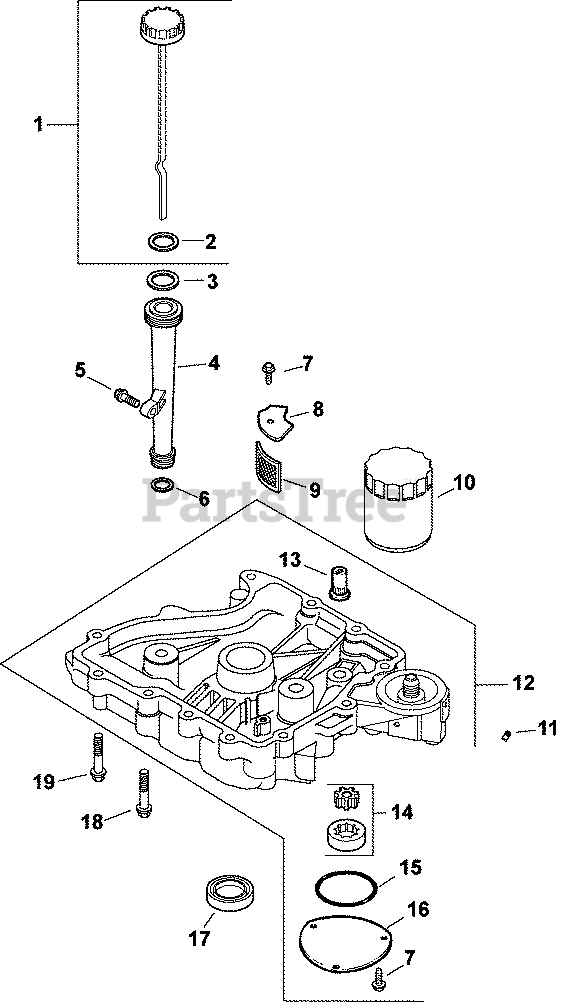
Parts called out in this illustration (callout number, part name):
1	DIPSTICK/CAP ASSY (BLACK)
2	O-RING, DIPSTICK
3	O-RING, UPPER OIL FILL TUBE
4	TUBE, OIL FILL USE 25 123 07-S
5	SCREW,FLG THD FRM M6X1.0X25-(#25086395S)
6	O-RING, LOWER OIL FILL TUBE
7	SCREW,FLG THD FRM M5X0.8X16-(#25086398S)
9	SCREEN, OIL-USE 24 162 26-S
10	OIL FILTER
11	PLUG, SQ HD PIPE 3/8"
12	PAN, OIL ASSEMBLY - DISCONTNUED
13	VALVE, OIL PRESSURE RELIEF
14	PUMP ASSEMBLY, OIL - DISCONTINUED
15	O-RING (2.5" DIA)
16	COVER, OIL PUMP
17	SEAL, OIL
18	SCREW, HEX FLANGE -USE 24 086 17-S
19	SCREW, FLG M8X1.25X45
